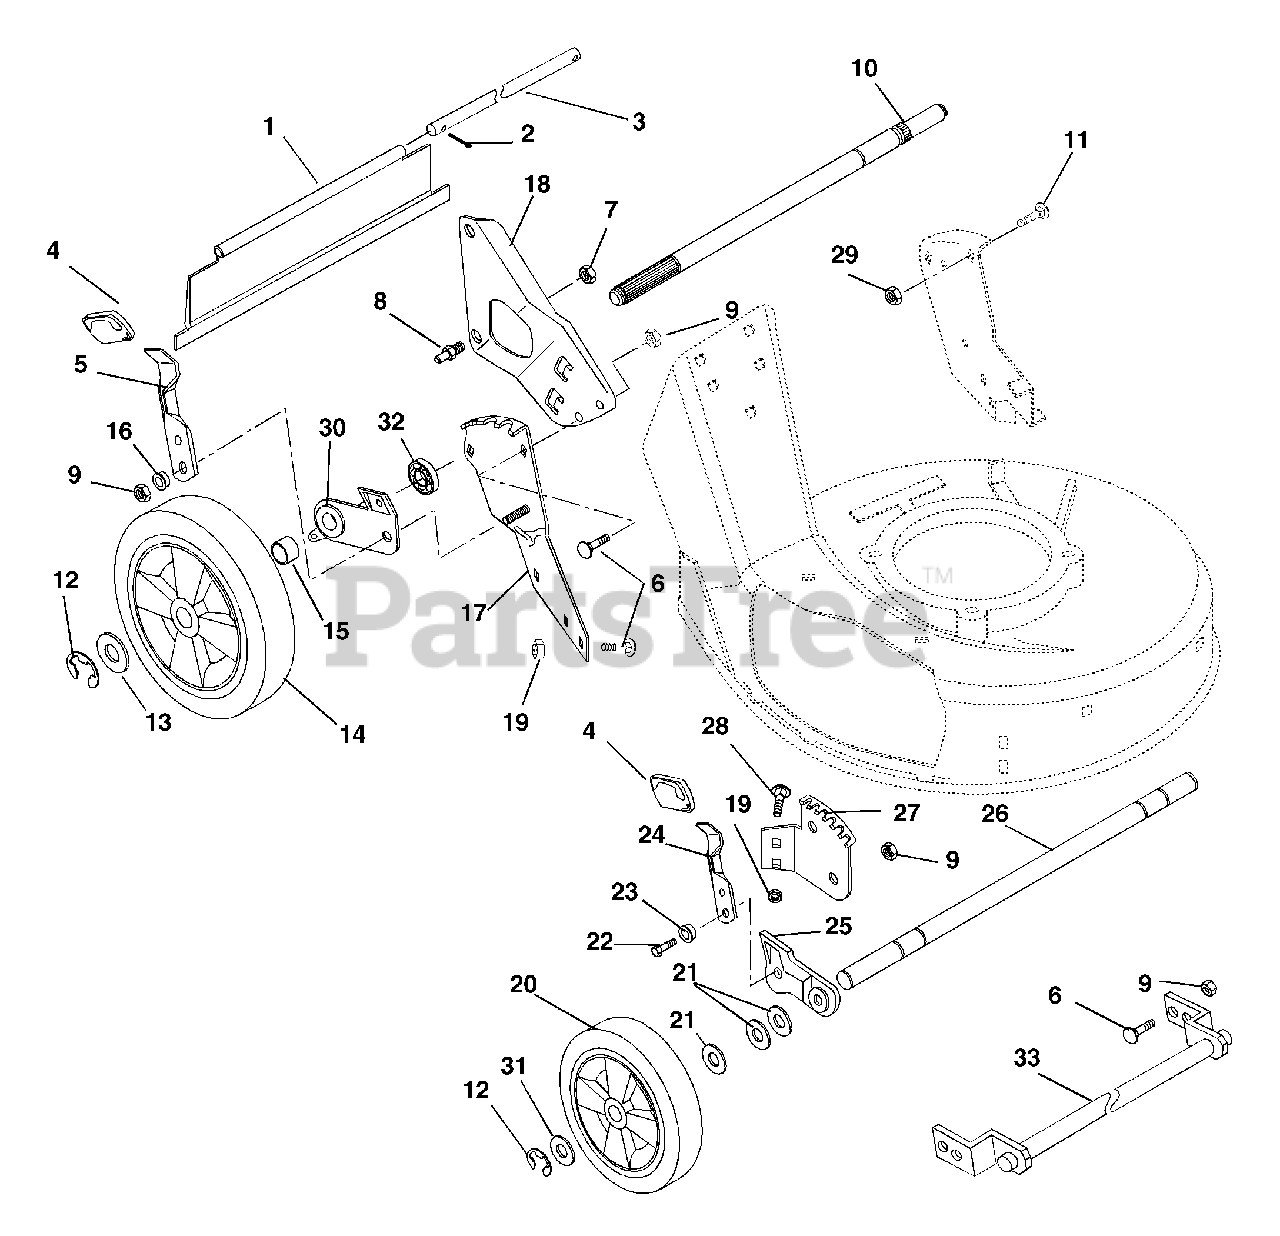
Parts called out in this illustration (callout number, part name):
1	REAR PROTECTIVE GUARD, S.P.
1	REAR PROTECTIVE GUARD, PUSH
2	@PIN-CTR .06X.50 EXTPRSQCT YWZ
3	ROD
5	HEIGHT ADJUSTMENT LEVER
6	@BLT-RHDSSQNK .31-18X.62 G5YZ
7	@NUT-LK-CTR .38-16 YWZC
8	HANDLEBAR STUD
9	@NUT-LK-CTR .31-18 YWZC
10	REAR AXLE,5/8 DIA
10	REAR AXLE-PUSH MOWER MM
11	BLT-RDHDSQNK .31-18X1.0 SHTYZ
12	RG-RTNG-EXT .500X.042 (E)
13	WSHR-FL-STL .505X.880X.072 YWZ
14	WHL, LH 10.50"
14	WHL, RH 10.50"
14	10 1/2 TIRE SKIN
14	TIRE, REAR 10X1.75 #6 GRAY
15	SPACER TUBE, SELF PROPEL
15	SPACER TUBE,PUSH LH
15	SPACER TUBE PUSH RH
16	BSHG-FLG .32X.500X.344X.880
17	QUADRANT, REAR LH
17	QUADRANT, REAR RH
18	RH HANDLEBAR MTG. BRKT
18	LH HANDLEBAR MTG. BRKT
18	RH HANDLEBAR MOUNT WELDMENT
18	LH HANDLEBAR MOUNT WELDMENT
19	@NUT-SPNLK-FLG .312-18 YWZC
20	WHL 7.50" .50 BORE, 1.50 HUB
20	TIRE, FRONT 7X1.50
21	WSHR-FL-STL .52X.827X.062 YWZC
22	@BLT-HEX .31-18X1.00 GR5 YWZC
23	BSHG-FLG .32X.500X.344X.880
24	FRONT HEIGHT ADJUSTMENT LEVER
25	LEFT ADJUSTOR BRACKET ASSEMBLY
25	RIGHT ADJUSTOR BRACKET ASSEMBL
26	FRONT AXLE
27	FRONT QUADRANT, LH
27	FRONT QUADRANT, RH
28	@BLT-RDHDSQNK .31-18X.50 G5YZ
29	@NUT-LK-NYL .312-18 YWZC
30	REAR ADJUSTMENT BRACKET L.H.
30	REAR BRACKET & BEARING ASSY RH
30	REAR BRACKET & BEARING ASSEMBL
30	REAR ADJUSTMENT BRACKET R.H.
30	L.H. REAR ADJUSTOR BRACKET
31	WSHR-FL-STL .505X.880X.072 YWZ
32	BRG-BALL .625X1.383X.50
33	DETHATCHER RETAINER WELDMENT
